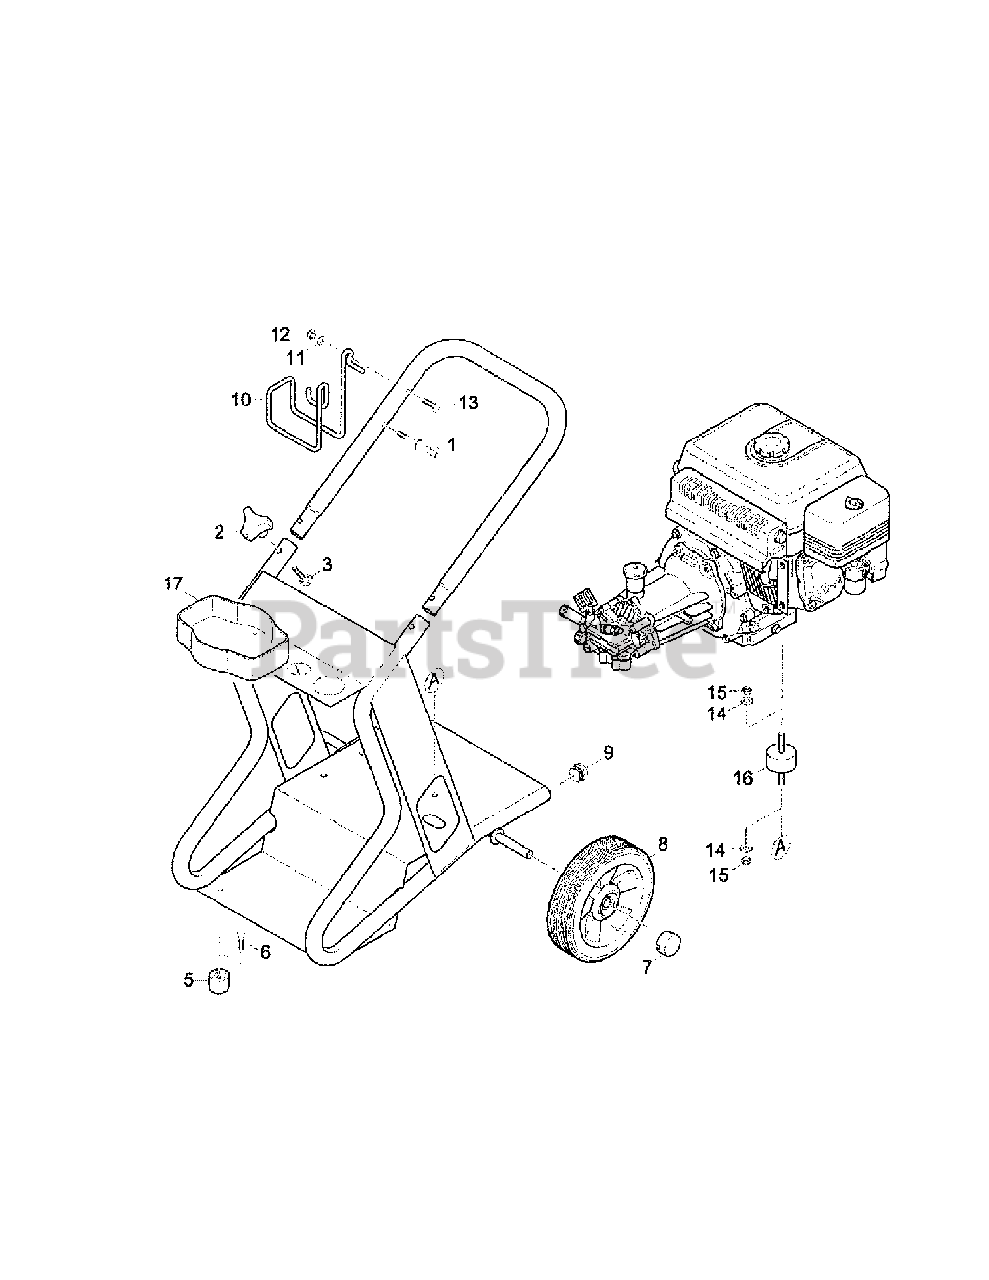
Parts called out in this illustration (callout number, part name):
1	Bolt
2	Control Knob
3	Screw
5	Rubber Bumper
6	Bolt
7	Cap
8	Wheel
9	Plug
10	Bracket
11	Washer
12	Nut
13	Screw
14	Washer
15	Nut
16	Spacer
17	Tray, 1 gal
